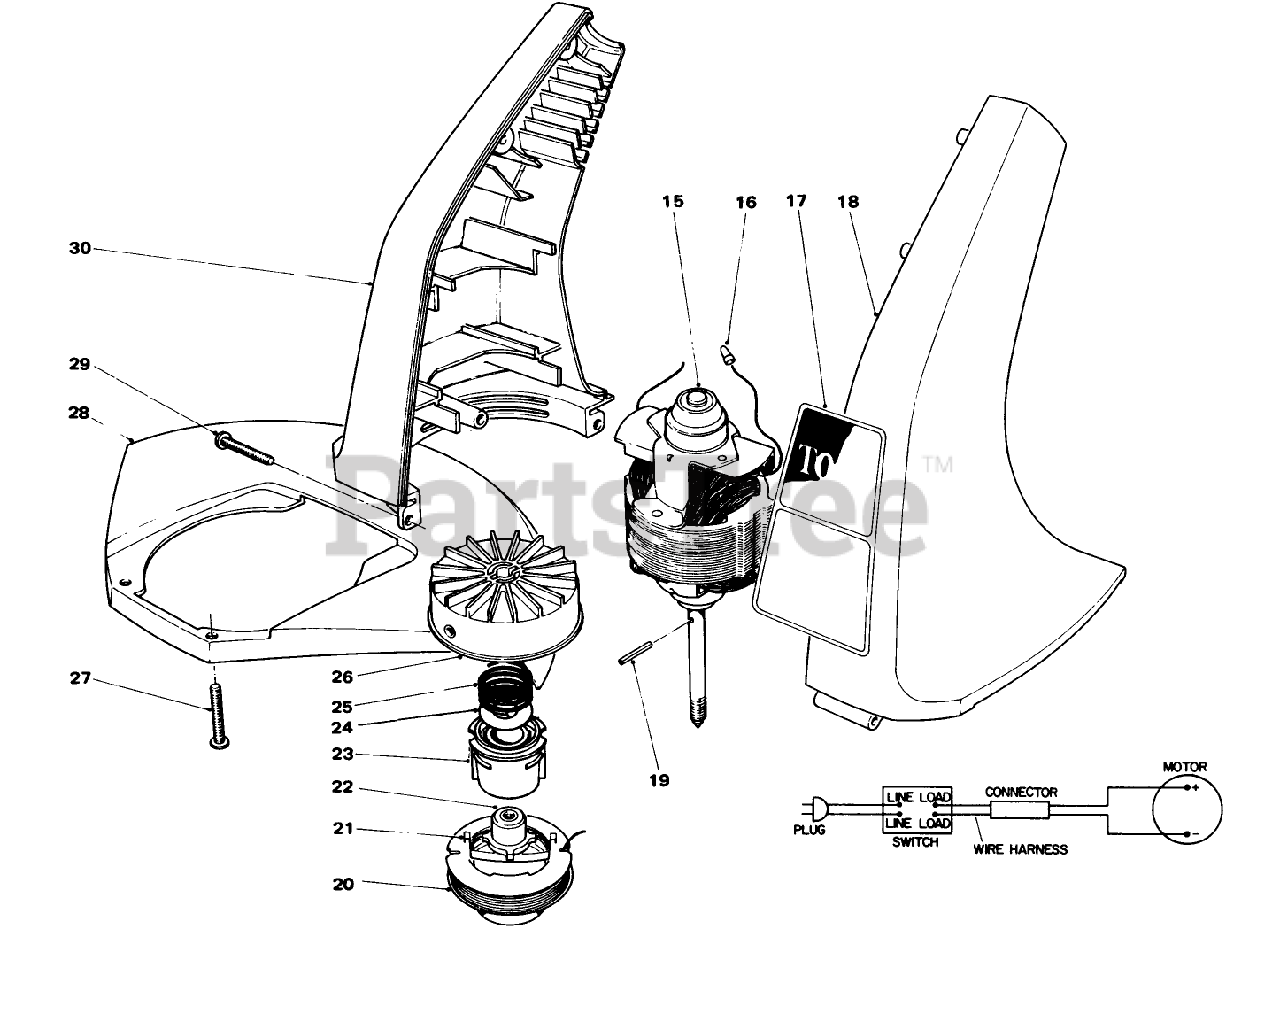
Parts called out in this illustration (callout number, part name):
15	Motor
16	CONNECTOR WIRE JOINT
17	1100 Decal
18	Housing-Left Hand
19	COIL PIN
20	Prewound Spool
21	SADDLE-SPOOL CAP
22	Driver
23	SPOOL CORE
24	WASHER-FLAT
25	SPRING COMPRESSION
26	DRUM W/EYELET
27	Screw
28	Shield
29	Screw
30	Housing-Right Hand
